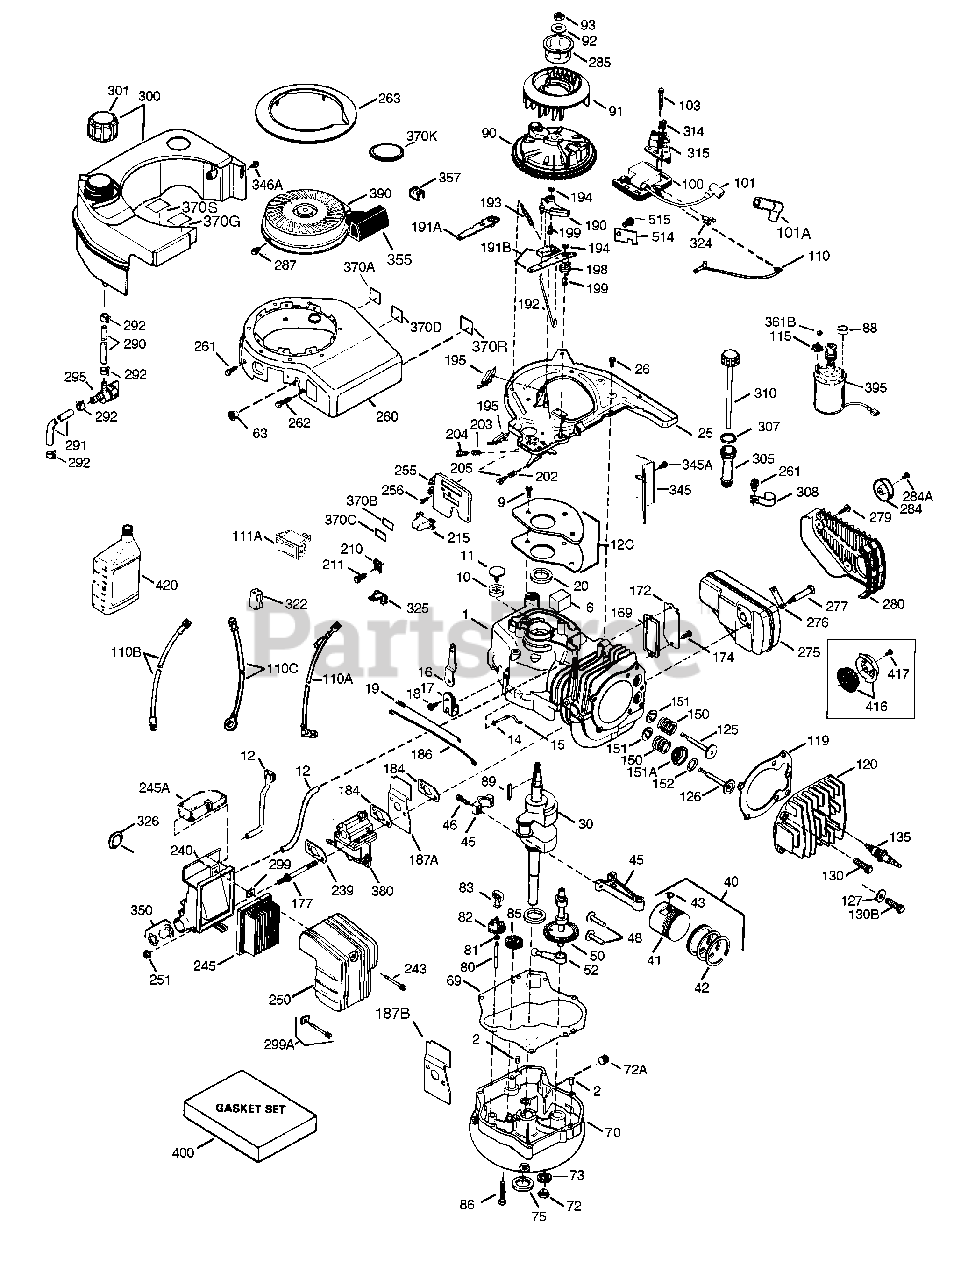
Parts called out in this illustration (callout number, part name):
1	"Cylinder (Incl. 2,10,12,20 & 125)
2	Dowel Pin
6	Breather Element
9	Screw, 10-24 x 3/4"
10	Breather Valve Body
11	Check Valve
12	Breather Tube
12C	* Breather Cover & Gasket
14	Flat Washer
15	Governor Rod (Machined)
16	Governor Lever
17	Governor Lever Clamp
18	Screw, Torx T-15, 8-32 x 19/64"
19	Governor Spring
20	Oil Seal
25	Blower Housing Baffle Ass'y. Incl.l95
26	Screw, 1/4-20 x 5/8"
30	Crankshaft
40	Piston,Pin,Ring Set (Std.)
40	Piston,Pin,Ring Set (.010 OS)
41	Piston & Pin Ass'y.(Std.) (Incl. 43)
41	Piston & Pin Ass'y.(.010 OS)(Incl.43)
42	Ring Set (Std.)
42	Ring Set (.010 OS)
43	Piston Pin Retaining Ring
45	Connecting Rod Ass'y. (Incl. 46)
46	Connecting Rod Bolt
48	Valve Lifter
50	Camshaft (MCR)
52	Oil Pump Ass'y.
69	* Mounting Flange Gasket
70	Mounting Flange (Incl. 72 thru 85)
75	Oil Seal
80	Governor Shaft
82	Governor Gear Ass'y. (Incl.81)
83	Governor Spool
85	Idler Gear
86	Screw, 1/4-20 x 1-9/16"
89	Flywheel Key
90	Flywheel
91	Flywheel Fan
92	Belleville Washer
93	Flywheel Nut
100	Solid State Ignition
101	Spark Plug Cover
103	Screw, Torx T-15, 10-24 x 15/16"
110	Ground Wire
119	* Cylinder Head Gasket
120	Cylinder Head
125	Exhaust Valve (Std.) (Incl. 151)
125	Exhaust Valve (1/32" OS)
126	Intake Valve (Std.) (Incl. 151)
130	Screw, 5/16-18 x 1-1/2"
135	Resistor Spark Plug - RJ17LM
150	Valve Spring
151	Lower Valve Spring Cap
151A	Intake Valve Seal
169	* Valve Spring Box Gasket
172	Valve Spring Box Cover
174	Screw, 10-24 x 9/16"
177	Carburetor Mounting Stud
184	Carburetor Gasket
186	Governor Link
187A	Air Baffle
190	Brake Lever Ass'y.
191B	Brake Control Lever
192	Brake Control Lever Link
193	Brake Spring
194	Retaining Ring
195	Terminal Ass'y.
198	Brake Control Lever Spring
199	Brake Lever Bushing
239	* Carburetor To Air Cleaner Gasket
240	Air Cleaner Body (Incl. 239 & 350)
245	Air Filter (Paper) (also available in Packaged Part #740031B for model VLV only) (also available in Packaged Pa rt #740061C for model OH195)
250	Air Cleaner Cover
251	Lock Nut 1/4-20
255	Control Plate
256	Screw, 8-32 x 1/2"
262	Screw, 1/4-20 x 1/2"
275	Muffler
276	Locking Plate
277	Screw, 5/16-18 x 2-11/32"
285	Starter Cup
287	Screw, 8-32 x 21/64"
290	Fuel Line (8.62")
292	Fuel Line Clamp
300	Fuel Tank (Incl. 301)
301	Fuel Cap
305	Oil Fill Tube
307	"O" Ring
308	Fill Tube Clip
310	Dipstick
325	Spring Clip
346A	Screw, 10-32 x 35/64"
370A	Lubrication Decal
370C	Decal - Primer 3X with Hand
370R	Warning Decal
380	Carburetor (Incl. 184,187A & 239)
390	Rewind Starter NOTE: This engine cou ld have been built with 590702 starte r.
400	* Gasket Set (Incl. items marked PK in notes). Incl. part #'s 27234A (1),28 833 (1), 36005A (1), 36032A (1),36061 (1), 37136 (1), 696088 (1)
416	Spark Arrestor Kit (Incl. 417) Option al
417	Screw, 10-32 x 1/2" (Optional)
900	Replacement Engine 750819C.
900	Replacement Short Block 750797C, orde r from 71-999.
999	Summer Maintenance Kit (incl. Oil, Sp ark Plug, Air Cleaner, & Ultra Fresh)
